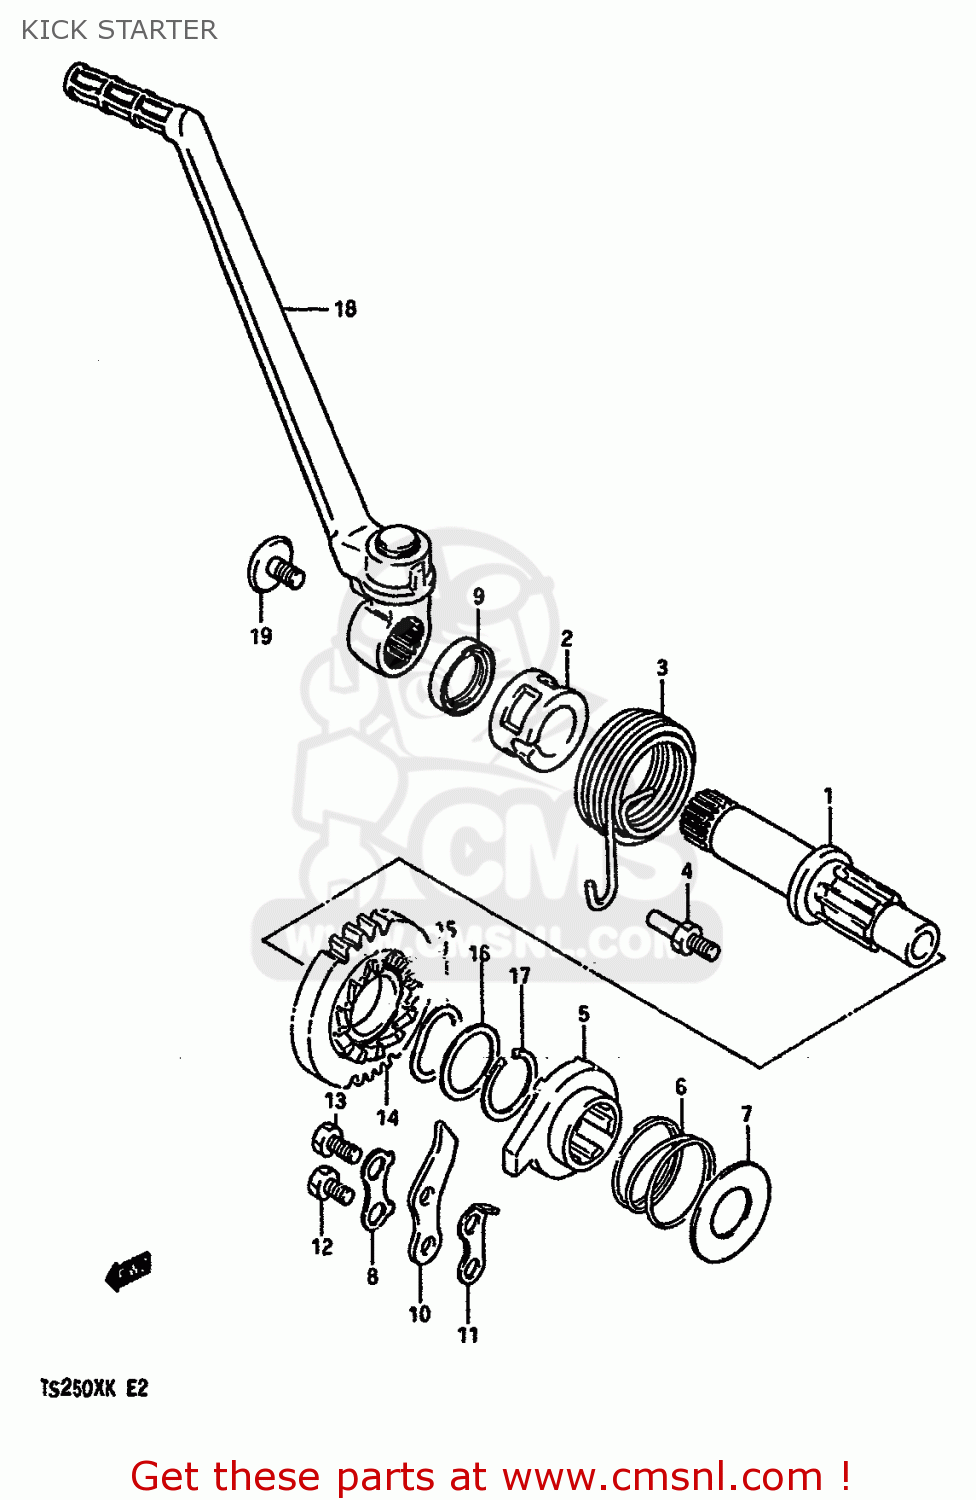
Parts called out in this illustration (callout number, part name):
1	SHAFT,KICK STARTER
2	GUIDE,KICK STARTER SPRING
3	SPRING
4	BOLT,KICK START SHAFT SPR HOOK
5	STARTER,KICK
6	SPRING
7	WASHER
8	WASHER
9	SEAL,OIL(20X27X5)
10	GUIDE,KICK STARTER
11	STOPPER,KICK STARTER
12	BOLT
13	BOLT
14	GEAR
15	WASHER
16	THRUST WASHER
17	CIRCLIP
18	LEVER ASSY,KICK STARTER STARTER
19	BOLT 8X14
